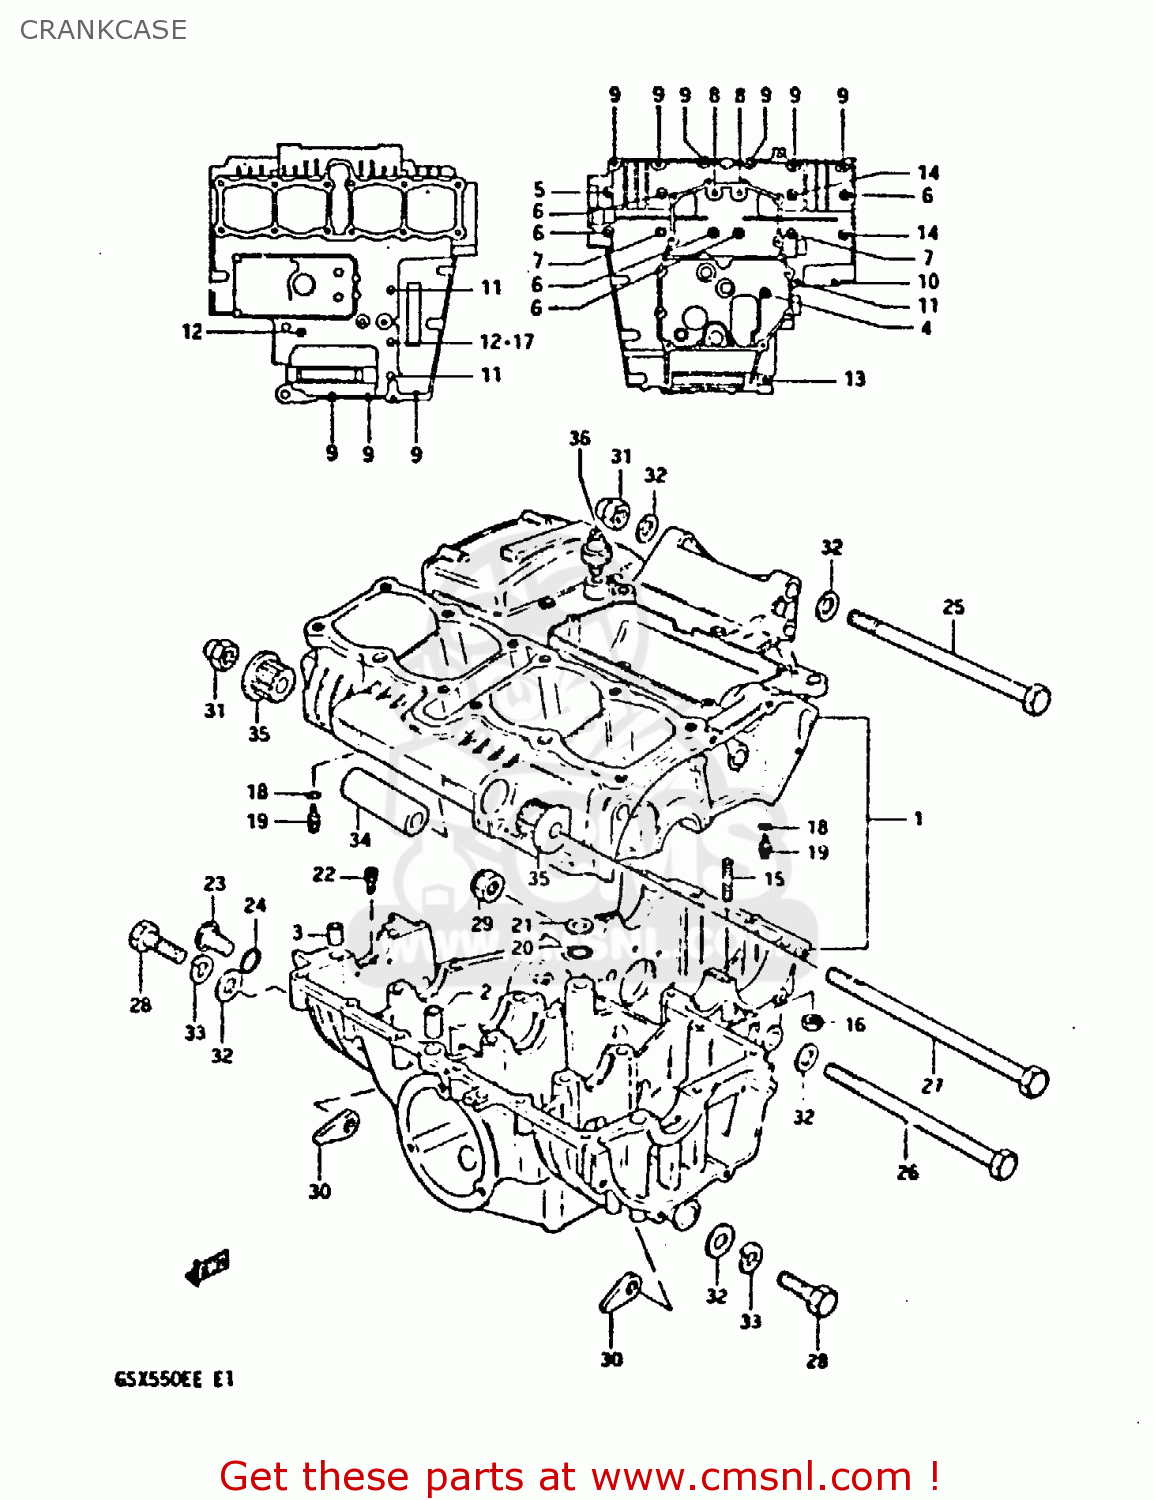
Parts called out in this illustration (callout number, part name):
1	CRANKCASE SET
2	PIN(10.4X13X22)
3	PIN (11X20)(SUS)
4	BOLT(6X100)
5	BOLT
6	BOLT(8X110)
7	BOLT
8	BOLT
9	BOLT
10	BOLT 6X55
11	BOLT
12	BOLT (5X95)
13	BOLT 8X60
14	BOLT (6X90)
15	STUD BOLT
16	NUT
17	GASKET(6.2X13X1.2) (NAS)
18	O RING(D:1.2,ID:4)
19	JET,OIL GALLERY
20	O RING(D:3.2,ID:12.9)
21	WASHER,THRUST
22	JET,AIR
23	PLUG
24	O RING(D:2.4,ID:16.8)
25	BOLT
26	BOLT
27	BOLT
28	BOLT
29	NUT 10MM
30	NUT
31	NUT
32	WASHER
33	LOCK WASHER
34	SPACER (10.2X16X105.5)
35	BUSH
36	SWITCH ASSEMBLY
